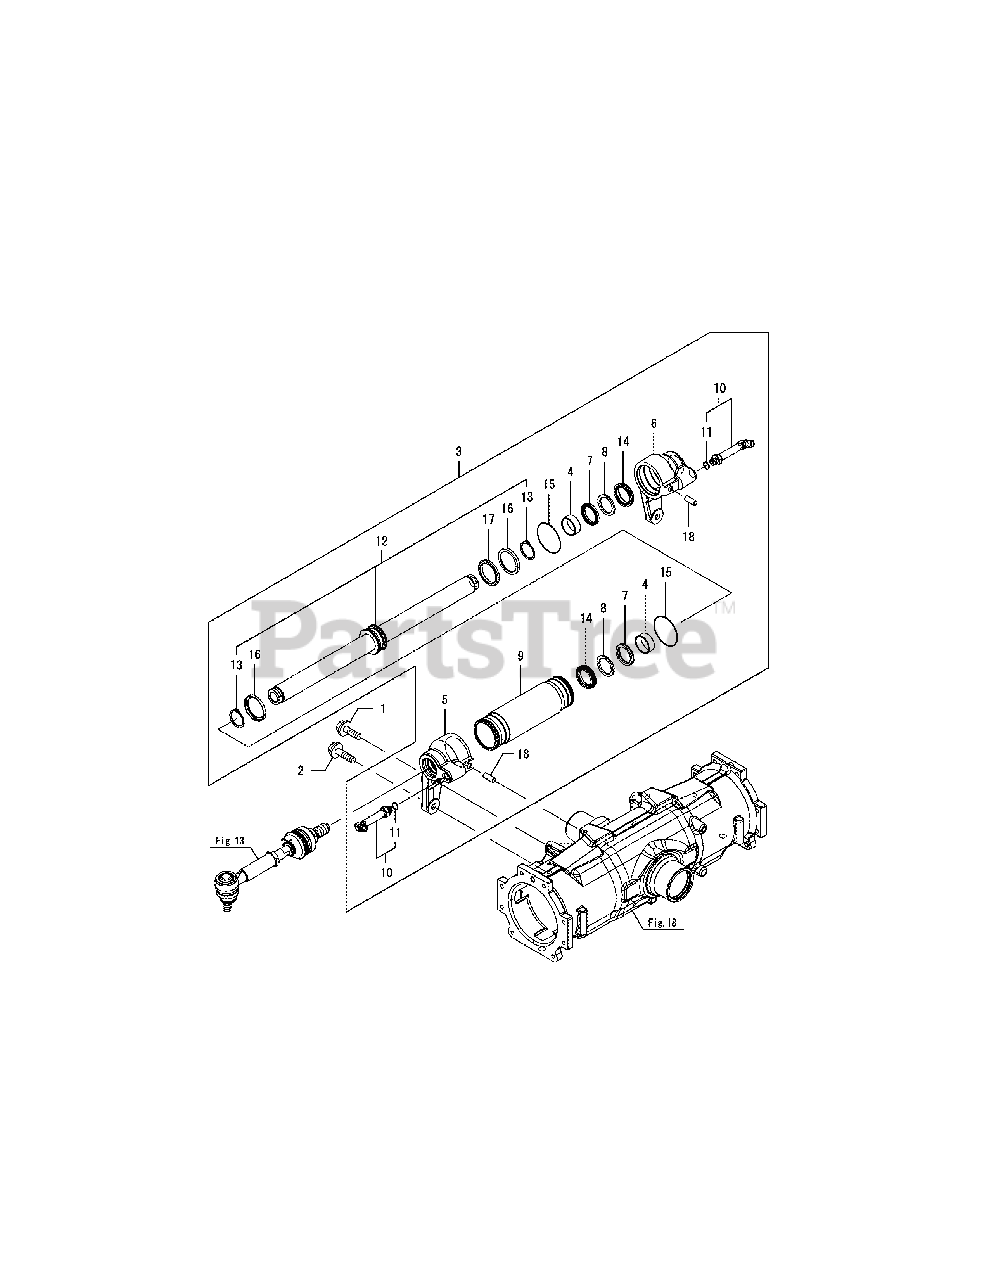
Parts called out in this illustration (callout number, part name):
3	CYLINDER ASSY, PST
4	BEARING, 35 X 15
5	CAP, CYLINDER L
6	CAP, CYLINDER R
9	TUBE, CYLINDER
11	O-RING 1B P-11.0
16	RING, BACKUP 55
17	PACKING,RGU 55
18	PARALLEL PIN, M10X20
